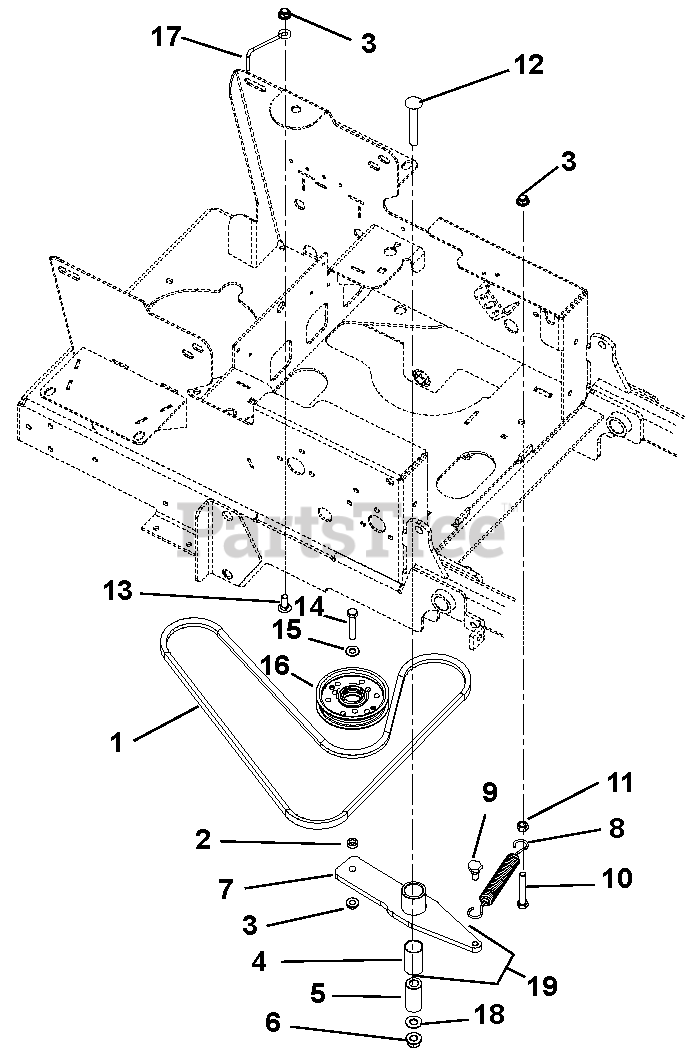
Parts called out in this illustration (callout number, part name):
1	Belt, 4L 67.47 Wrapped
2	Washer, Flat Steel .406 x 1.375 x .135
3	Nut, .38-16 Nyloc Flange
4	Bushing, 1.00 x 1.125 x 1.936
5	Bushing, Spacer .502 x .997 x 2.03
6	Nut .50-13 Nyl oc Flange
7	Weldment, Hydro Drive Idler Arm
8	Spring, Extension
9	Bolt, Shoulder EP .38-16 x .30 Hex
10	Bolt, Hex .38-16 x 2.50 Grade 5
11	Nut, Locking Center .375-16
12	Bolt, Hex .50-13 x 3.25 Grade 5
13	Bolt, Round Head Square Neck .38-16 x 1.00 Grade 5
14	Bolt, Hex .38-16 x 2.00 Grade 5
15	Washer, Flat Steel .406 x .812 x .065
16	Assembly, 4" Idler (.75 Wide)
17	Belt Finger
18	Washer, Flat Steel .511 x 1.441 x .125
19	Assembly, Idler Pivot Arm (Includes items 4, 7)
